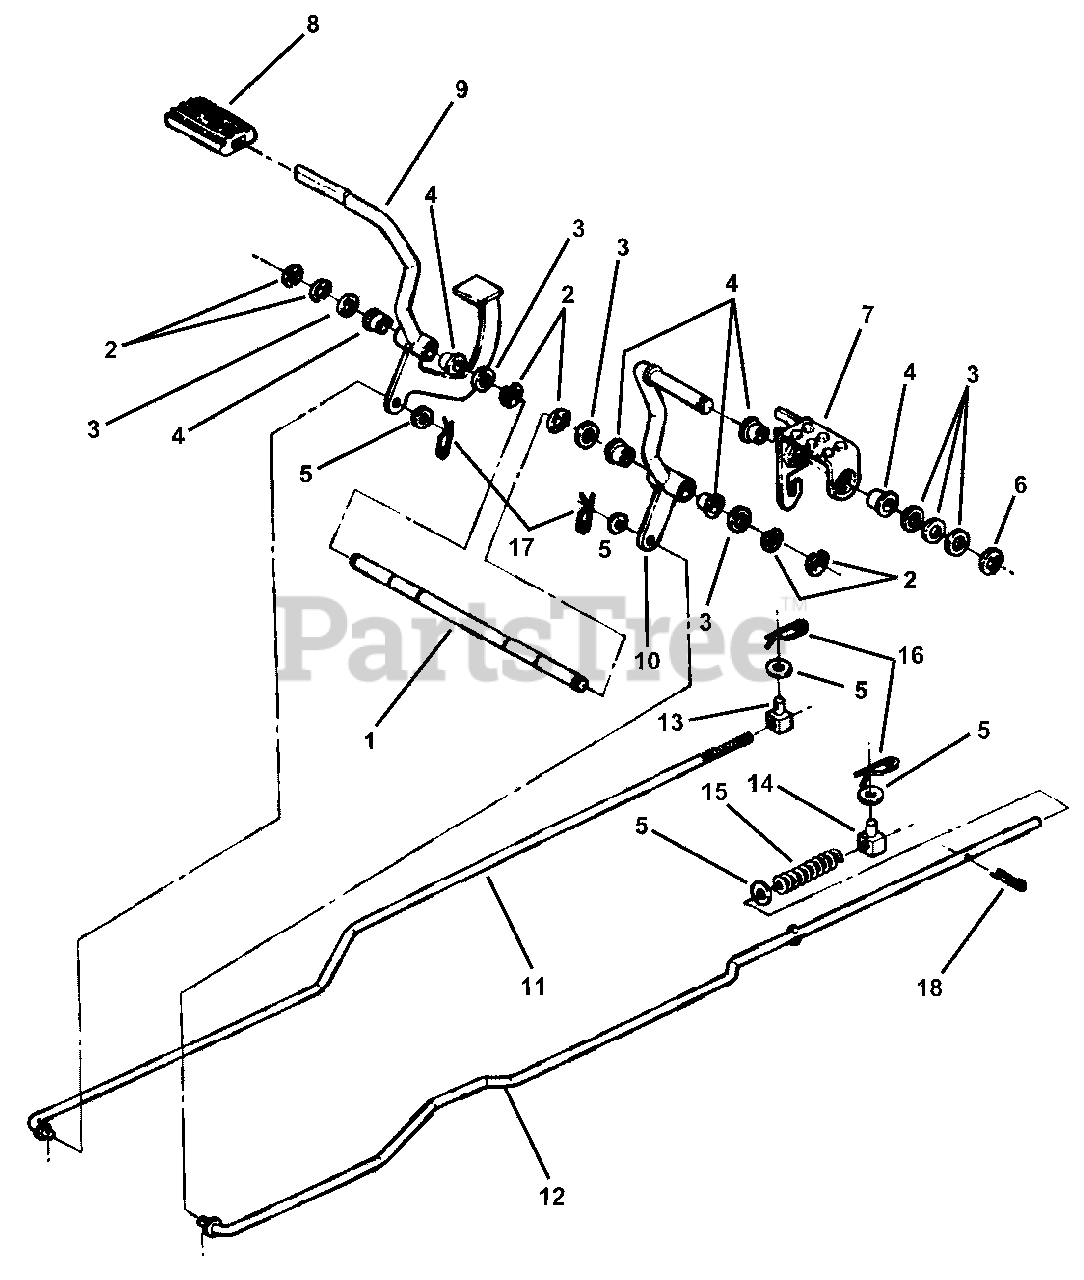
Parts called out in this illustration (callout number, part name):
1	SHAFT, Forward/Reverse/Brake Pedals
2	RING, External Retaining (5/8" Shaft)
3	WASHER, .64 I.D. x .99 O.D. x .05 Thick, Flat
4	BUSHING, Nylon
5	WASHER, 3/8" Flat
6	RING, 5/8" External Retaining
8	PAD, Pedal
9	WELDMENT, Forward/Reverse
10	WELDMENT, Brake
11	ROD, Accelerator
12	ROD, Brake
13	SWIVEL, Brake Link- PM
14	SWIVEL, Brake Link- PM
15	SPRING, Brake Compression
16	COTTER-PIN, 1/16" x 1.42" Self-Locking
17	PIN, 3/8" Self-Lock Cotter
18	PIN, 3/32 x 1/2" Cotter
